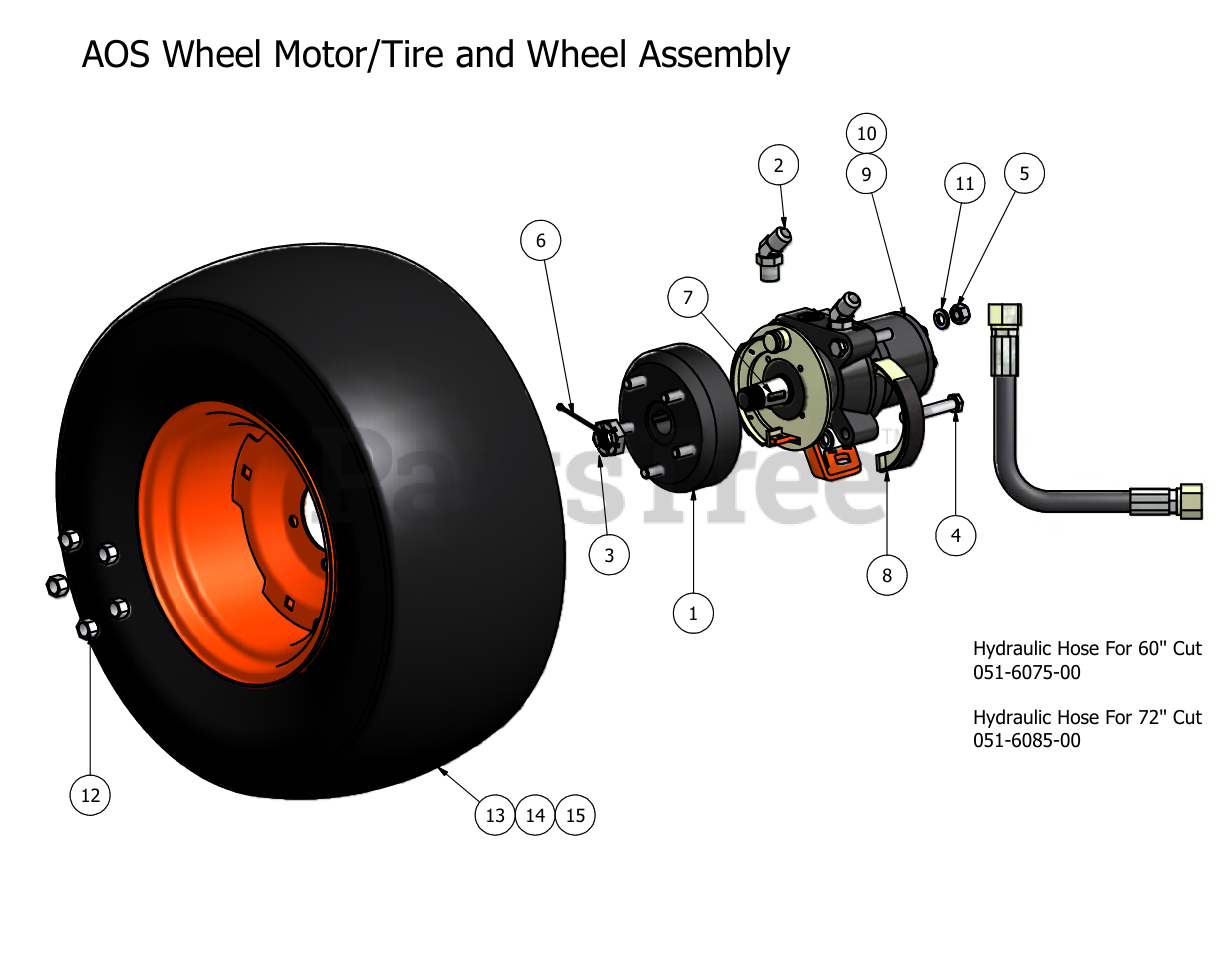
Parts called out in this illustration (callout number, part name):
1	Brake Drum
2	Hydraulic Fitting
3	Castle Nut
4	1/2" 13 x 3" GRS Hex - Bolt Zinc
5	1/2" Hex Nut
6	1/8"x2 1/4" Cotter Pin
7	Woodruff Key
8	Brake Pads
9	Wheel Motor and Drum Brake Combo-18E Right
10	Wheel Motor and Drum Brake Combo-18E Left
11	1/2" Lock Washer
12	Acorn Lug Nut
14	26" x 12-12 Tire -60"&72" Cut
15	26" Tire and Wheel Assembly
